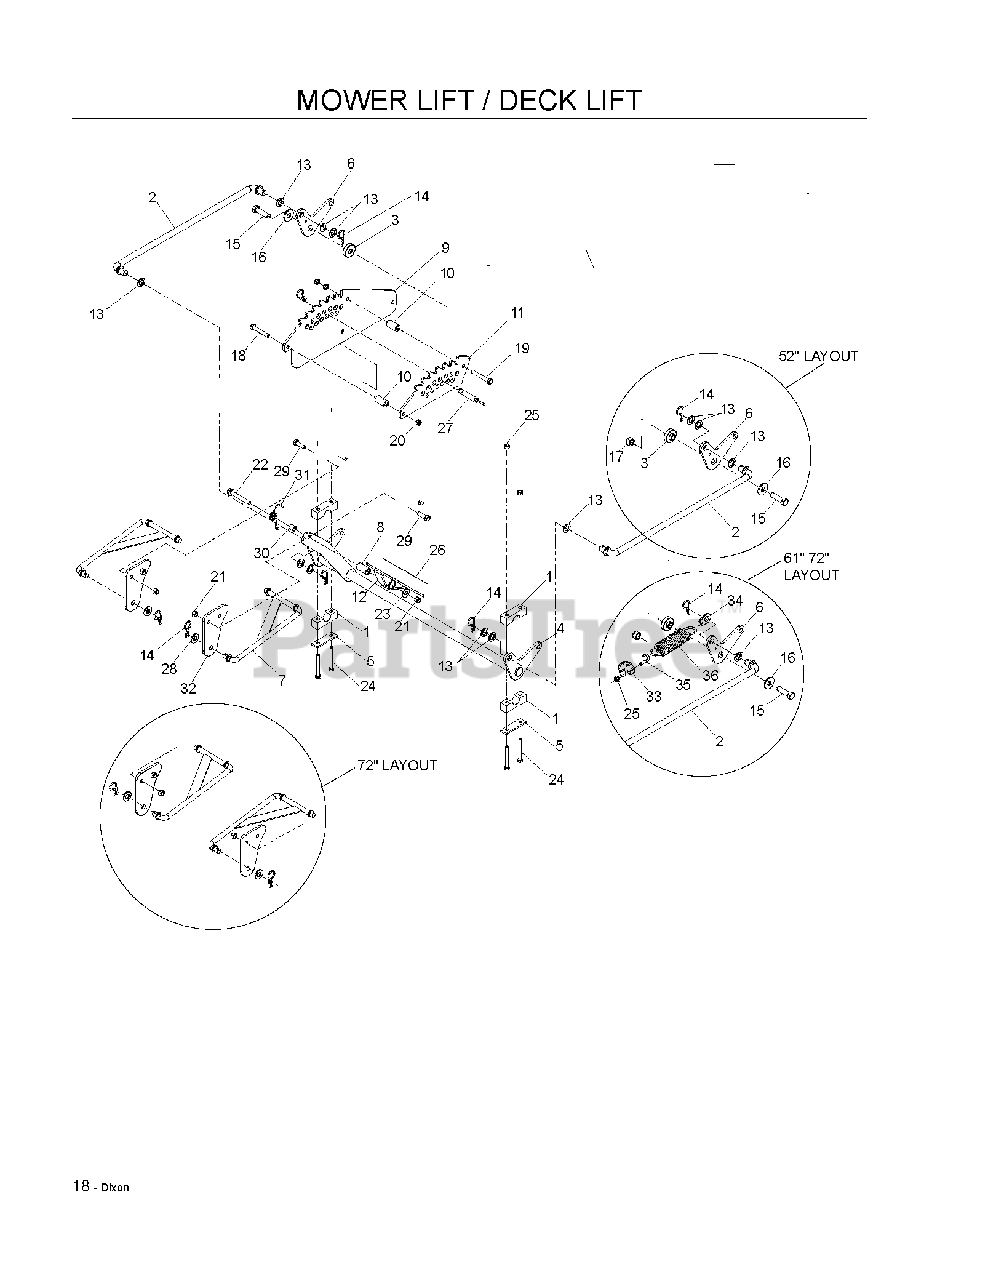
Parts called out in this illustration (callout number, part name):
1	PILLOW BLOCK
2	CROSS LINK
3	IDLER SPACER
4	SHAFT, LIFT, DECK
5	REINFORCEMENT BAR
6	BELLCRANK, REAR LIFT
7	STRUT LINKAGE
8	BUSHING, SLEEVE
9	PLATE, HEIGHT, MAIN, BLUE
10	DECK LIFT SPACER
11	PLATE, HEIGHT, BLUE
12	PEDAL, FOOT, WELDMENT
13	BUSHING
14	PIN, COTTER 1 3/4
15	HCS 1/2-13 X 1 3/4 GR 8
16	WASH USS FLAT 1/2
17	NUT 1/2-13 HEX NYLOC ZD
18	HCS 3/8C X 2 1/4
19	HCS 3/8C X 2 1/2
20	NUT HEX 3/8-16 NYLON, THIN
21	NUT 3/8-16 NYLOC
22	HHFS 3/8-16 X 2 3/4
23	WASHER 3/8 FLAT
24	HCS 5/16C X 2-3/4
25	5/16-18 NYLOC FLANGE NUT
26	FOOT PAD
27	HITCH PIN
28	WASHER 1/2" FLAT
29	HCS 3/8C X 1 1/4 GR5
31	SPRING, TORSION
32	MOUNT, STRUT
33	MOUNT, SPRING
34	TAB, SPRING
